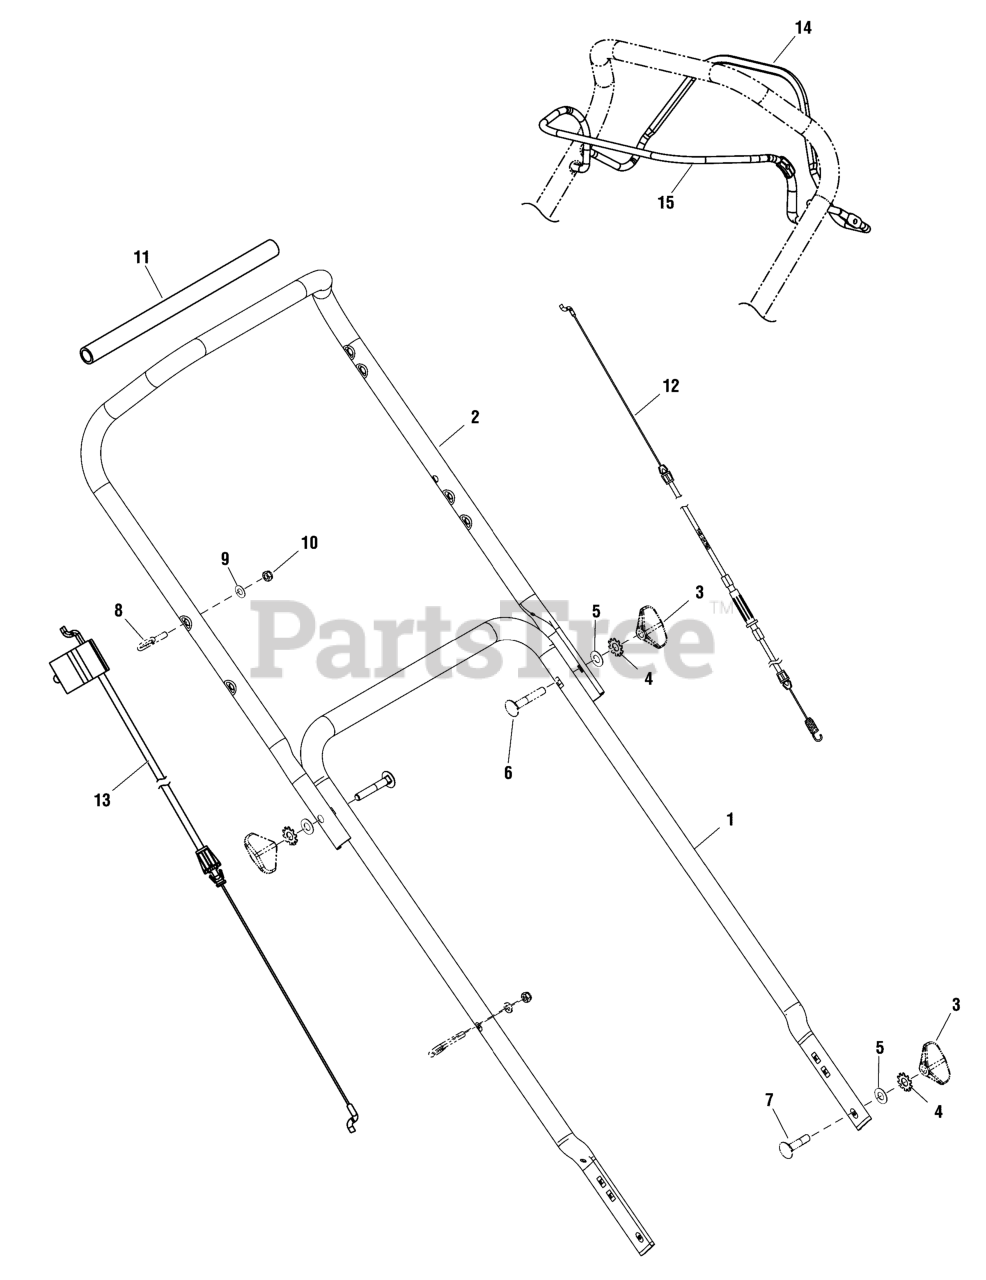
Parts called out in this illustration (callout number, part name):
1	HANDLE, Lower
2	HANDLE, Upper
3	NUT, Wing, M8 x 1.25
4	WASHER, B8.4
5	WASHER, Flat, A8.4
6	SCREW, M8 x 50
7	SCREW, M8 x 25
8	GUIDE, Starter Rope, M6
9	WASHER, A6.4 DIN 125
10	NUT, Hex Nylock, M6-1
11	TUBING, Foam
12	CABLE, Drive Control
13	CABLE, Engine Brake, 42.10
14	LEVER, Drive
15	LEVER, Engine Stop
